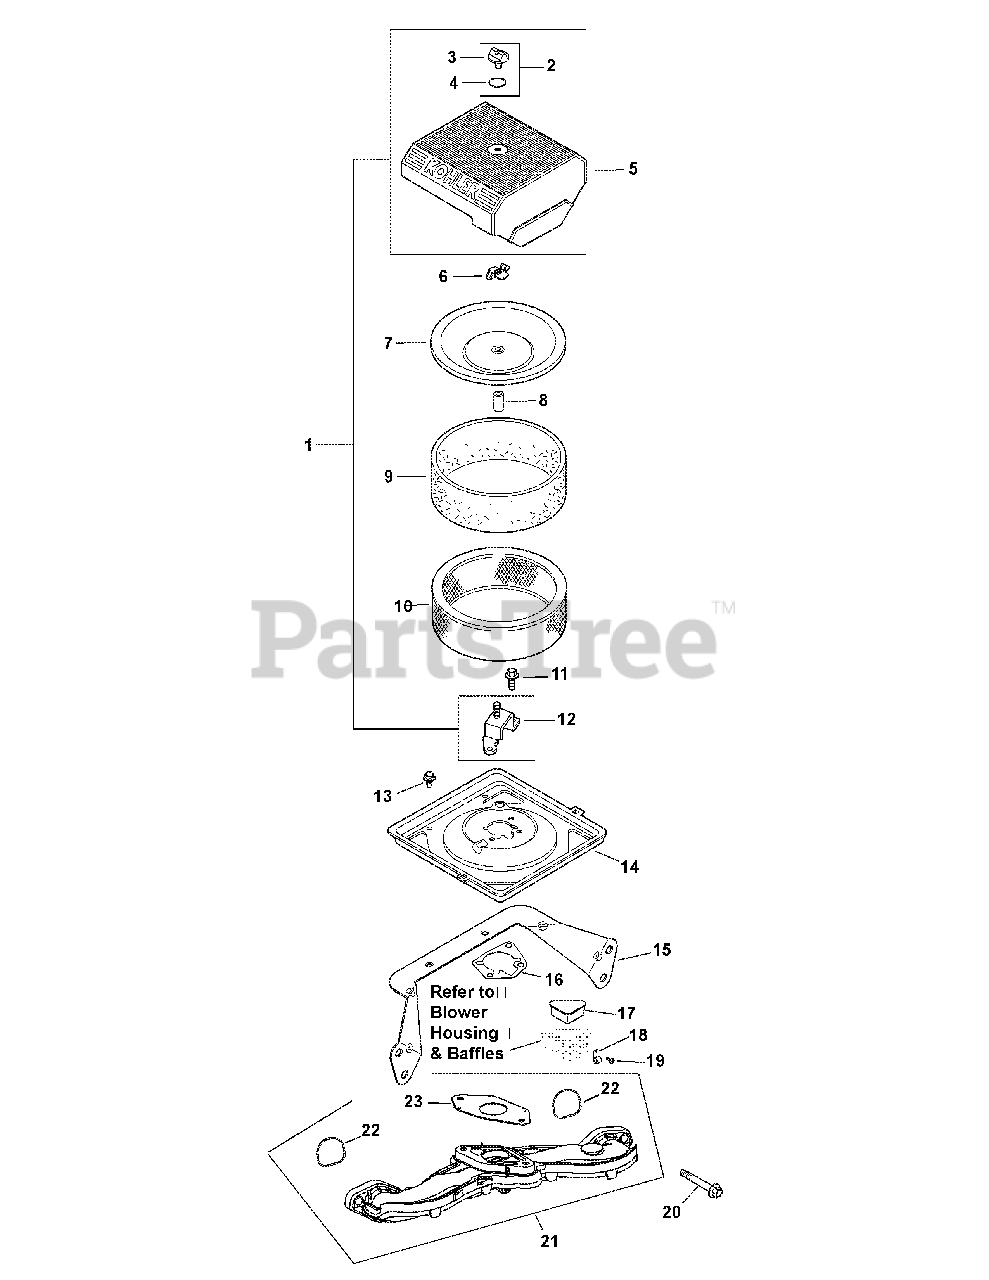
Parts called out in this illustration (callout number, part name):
1	Kit, air cleaner cover
2	Kit, knob w/seal
5	Cover, air cleaner
7	Cover, inner air cleaner
8	Seal, inner air cleaner
9	Element, precleaner
10	Element, air cleaner
11	Screw, flg thd frm M6x1.0x16
12	Bracket, air cleaner
13	Screw, flg thd frm M5x0.8x10
14	Base, air cleaner
15	Bracket, air cleaner base
16	Gasket, air cleaner base
17	Cover, blower housing
19	Screw, wsh hd tap #8-18x1/2"
20	Screw, flg M6x1.0x40
21	Manifold, intake - plastic
22	O-Ring, intake port
23	Gasket, carburetor
